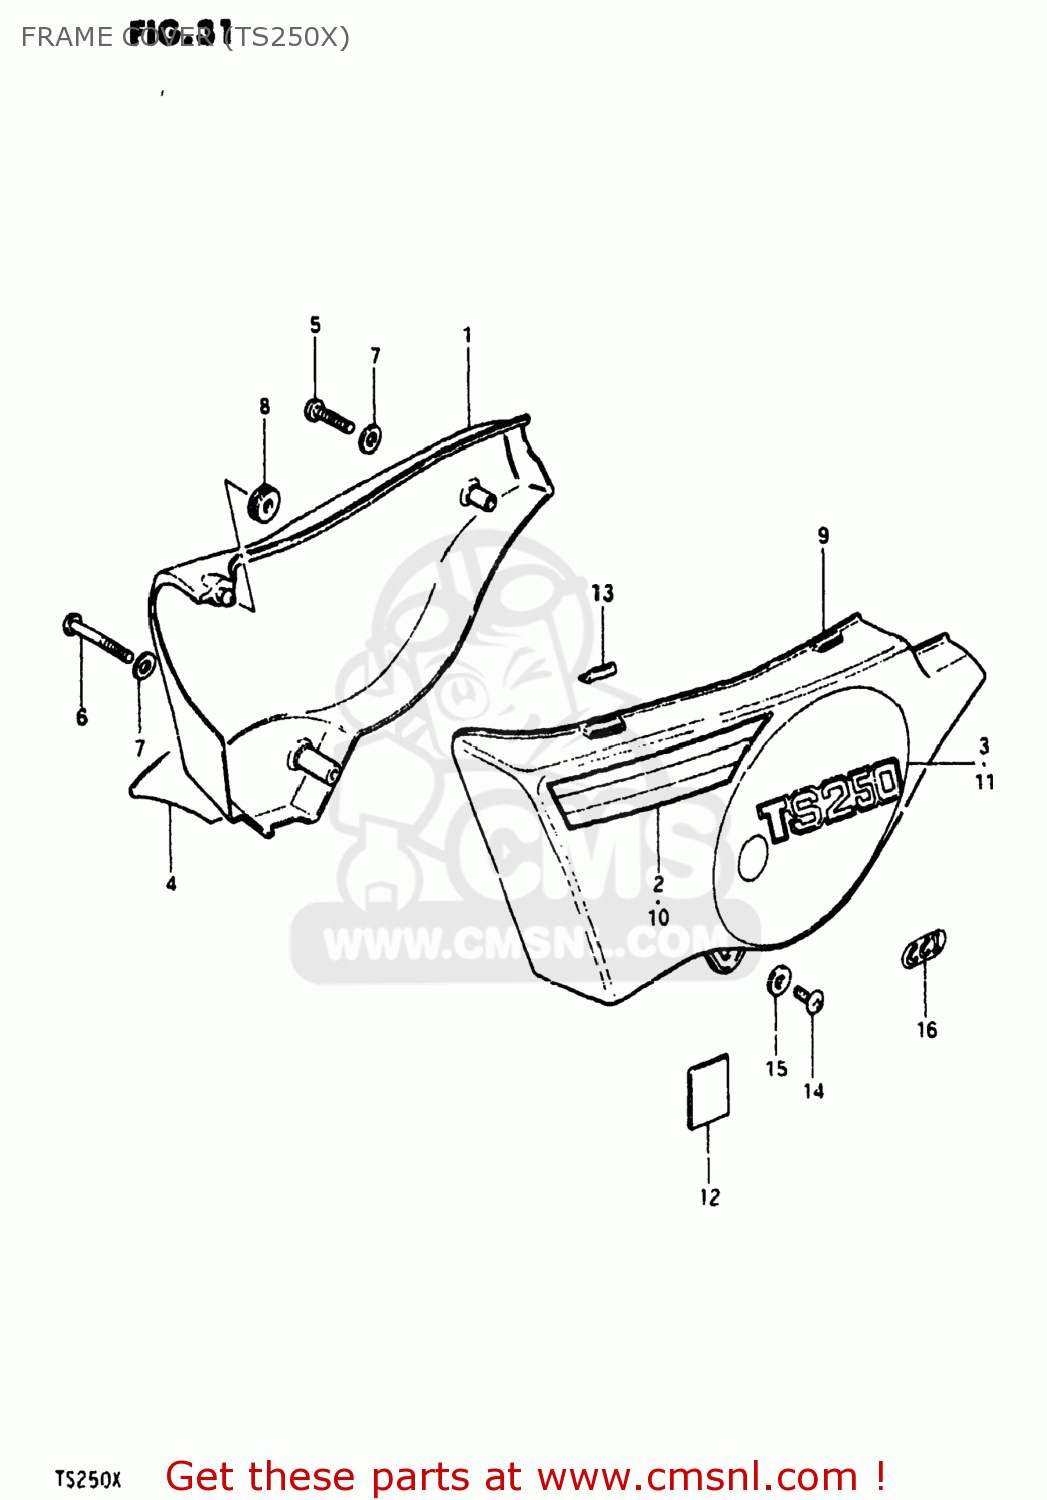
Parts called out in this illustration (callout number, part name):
1	COVER,FRAME,RIGHT
2	TAPE,FRAME COVER
3	EMBLEM
4	EMBLEM,FRAME COVER,RIGHT
5	SCREW
6	SCREW
7	WASHER
8	CUSHION
9	COVER,FRAME,LEFT
10	TAPE,FRAME COVER,LEFT
11	EMBLEM,FRAME COVER
12	PROTECTOR(170X95X3.0)
13	CUSHION,FRAME COVER
14	SCREW
15	WASHER
16	EMBLEM,CCIS
